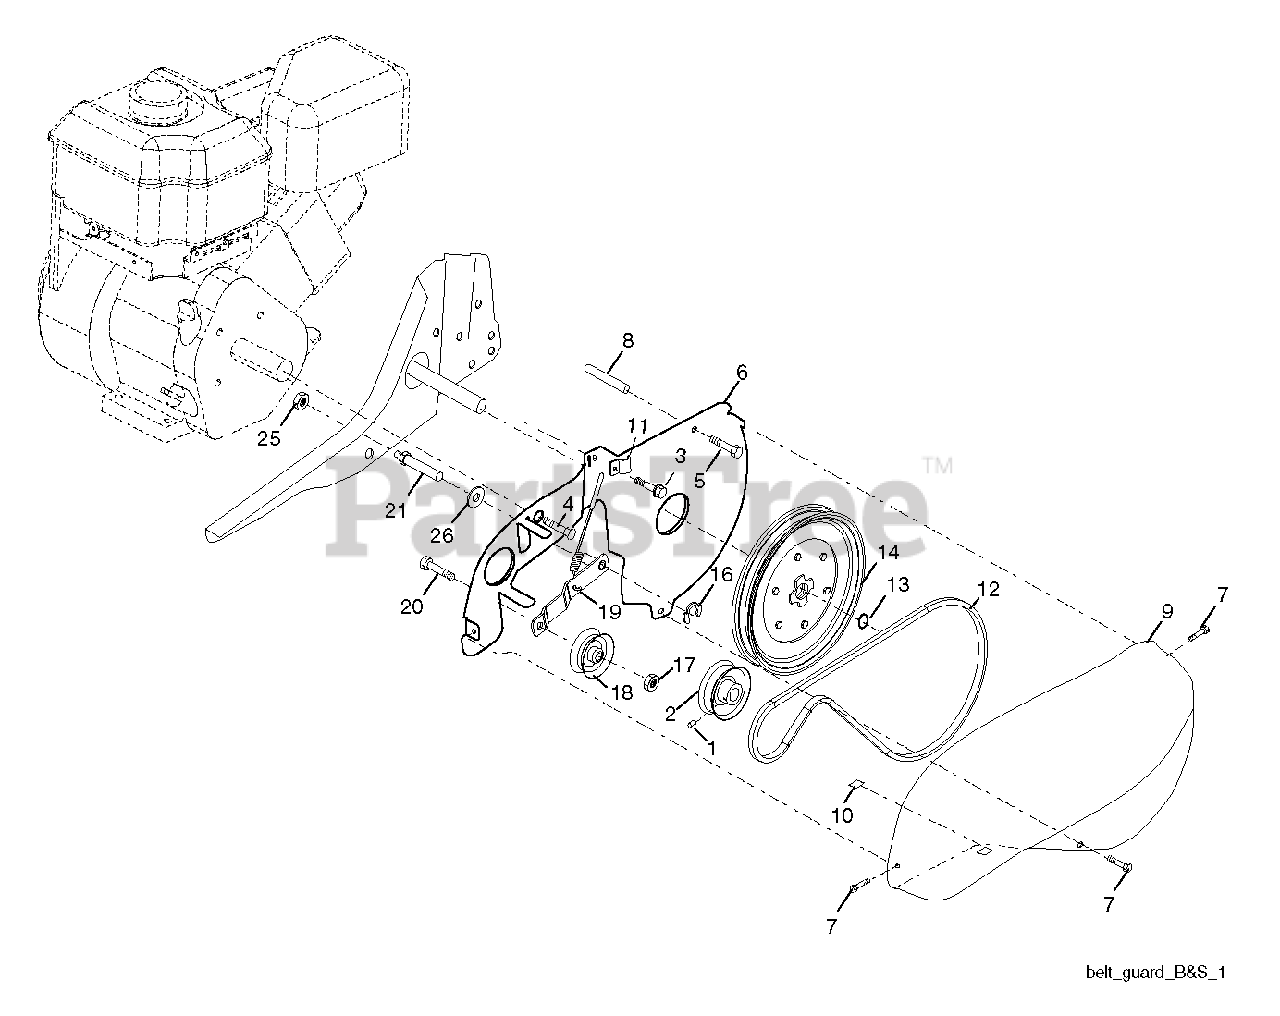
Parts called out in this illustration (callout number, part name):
1	SET SCREW
2	ENGINE PULLEY
3	SCREW.HXTAP.10-24
5	BOLT, THD ROLLER 1/4-20 X 2-1/
6	SHIELD.INNER.FRT.BLACK
7	SCREW.HEX.WSH.SLT.#10-24X.50
9	GUARD, BELT
10	PAD IDLER TI
11	CLIP.PLATED
12	V BELT STD
13	RETAINING RING LT
14	SHEAVE.TRANS
16	KLIP RING TI
17	NUT
18	PULLEY, IDLER
21	SHAFT.IDLER.TILLER
25	JAM NUT TI
